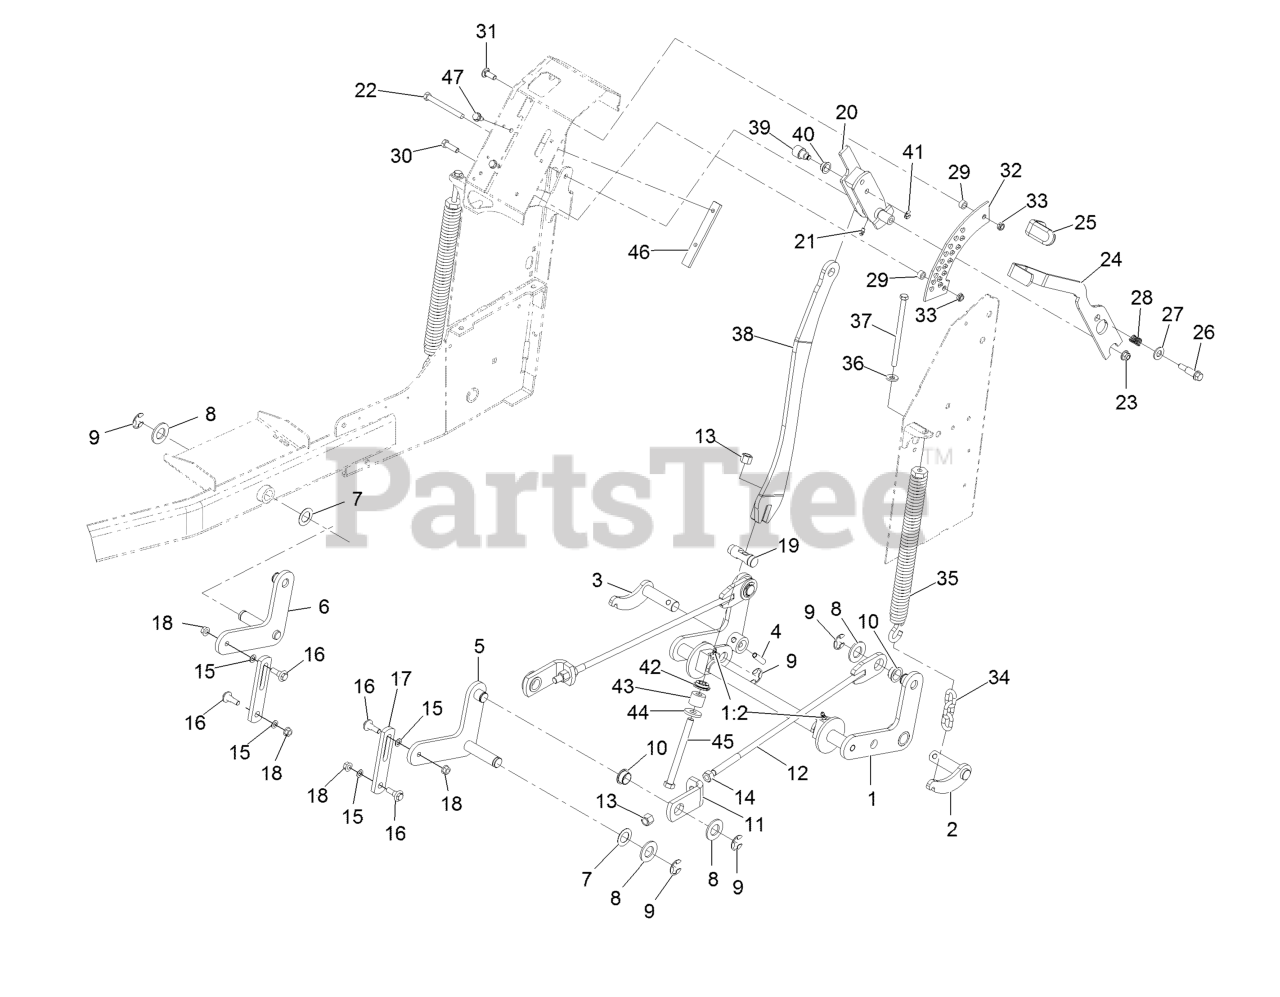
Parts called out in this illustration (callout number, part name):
1	Rear Crossshaft ASM
1:2	Zerk-45deg 1/4-28
2	Shaft-Pivot, LH
3	Shaft-Pivot, RH
4	Pin-Spiral
5	Arm-Lift, LH
6	Arm-Lift, RH
7	Washer-Thrust
8	Washer-7/8 SAE
10	Bearing-Flange
11	Bracket-Lift Rod
12	Lift Rod ASM
13	Nut-Nyloc 1/2-13
14	Nut-Hex 1/2-13
16	Screw-Hex Flange 3/8-16 X .80
17	Link-Lift
18	Nut-3/8-16 Flanged Side Lock
19	Pin-HOC
20	HOC Handle ASM
21	Zerk 1/4-28 Str Thrd Forming
22	Screw-HH 3/8-16 X 3 3/4
23	Nut-Nyloc 3/8-16 Flg
24	Lever-HOC
25	Grip-Lever
26	Screw-Shoulder
27	Washer-1/2 SAE
29	Bushing
30	Screw-HH 3/8-16 X 1 1/4
31	Bolt-Carriage 3/8-16 X 1
32	Bracket-HOC
33	Nut-Nyloc 3/8-16 Thin
34	Chain-Decklift
35	Spring-Extension
36	Washer-Spring Disc 3/8
37	Bolt-HH 3/8-16 X 6 Tap
38	Bar-Lift
39	Hub-Pivot
40	Bearing-Flange
41	Ring-Retaining
42	Seat-Spring
43	Spring-Urethane
45	Screw-HH 1/2-13 X 5 1/2
46	Skid-Handle, Lift
47	Screw-HWH 5/16-18 X 3/4 Tf
